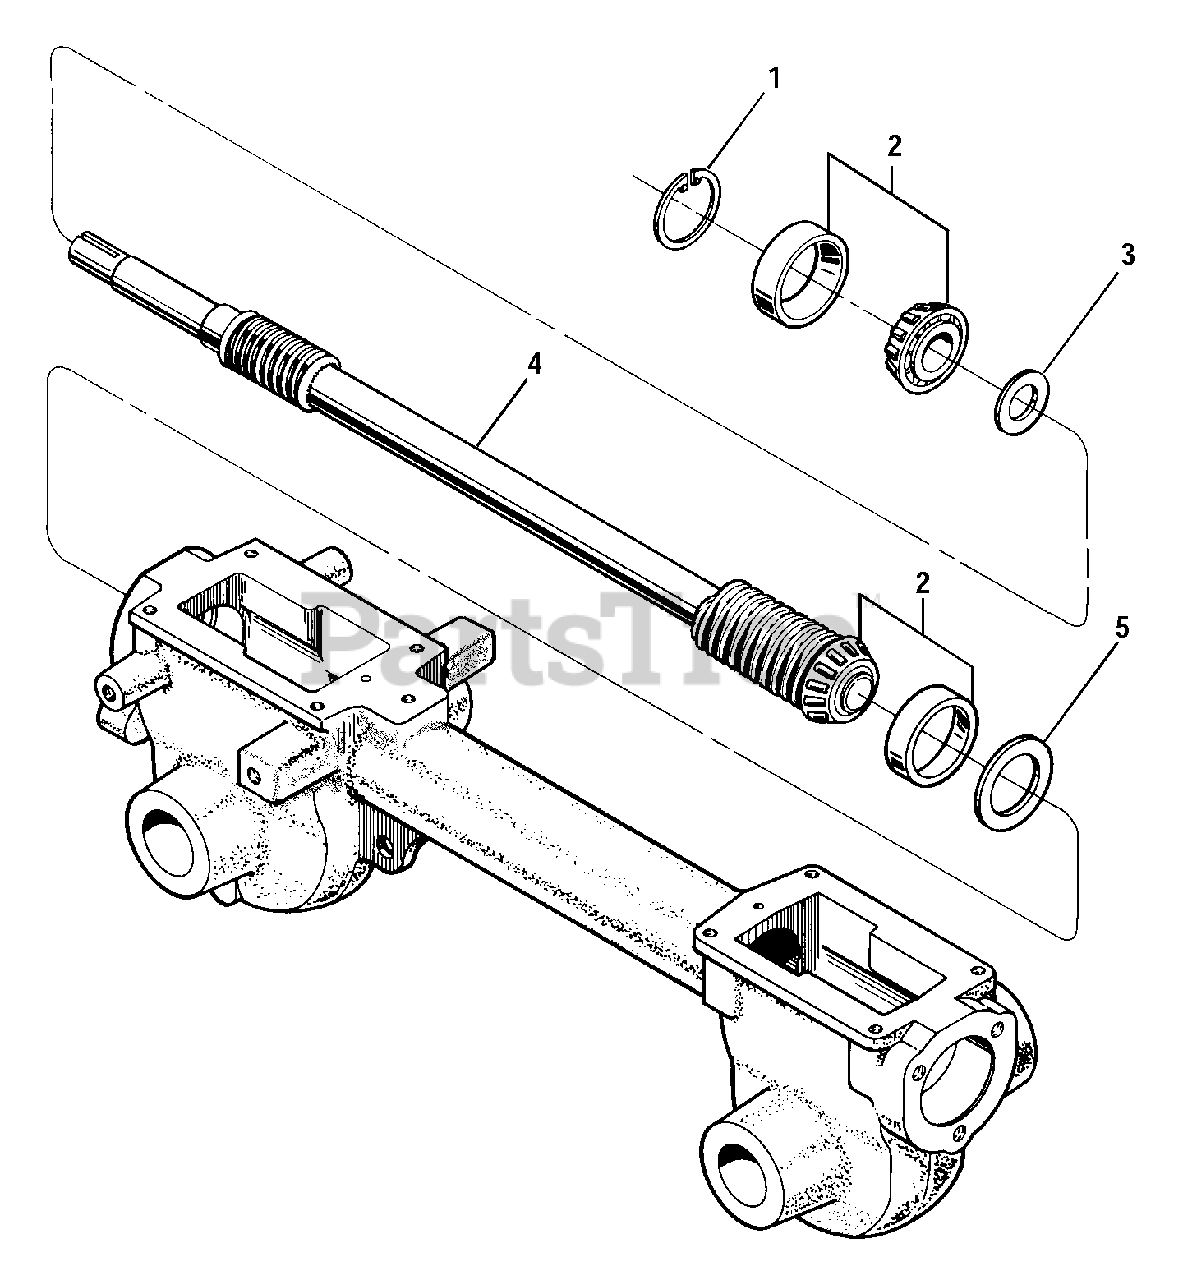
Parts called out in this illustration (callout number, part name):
1	Snap Ring
2	Bearing, Tapered Roller (with race)
3	Support Washer, Rear
4	Drive Shaft
5	Shim, Rear Bearing Cap,.010" thick
